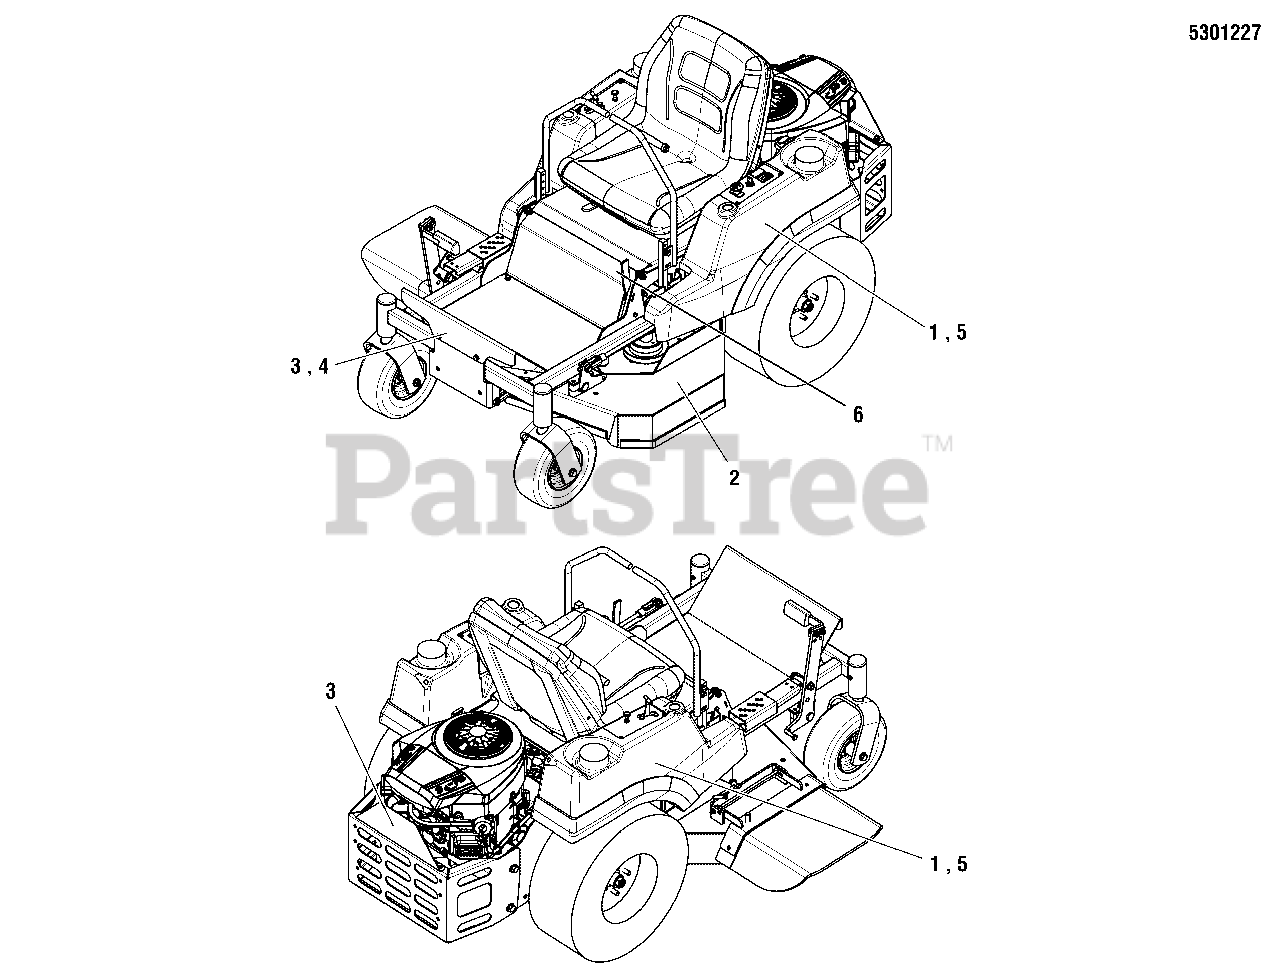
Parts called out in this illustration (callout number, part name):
1	DECAL, LOGO
2	DECAL, MOWER WIDTH, 48IN/122CM
3	DECAL, SNAPPER, FRONT
4	DECAL, LOGO P9 PANEL
5	DECAL, SNAPPER LOGO
6	DECAL, MODEL SERIES, 400Z
